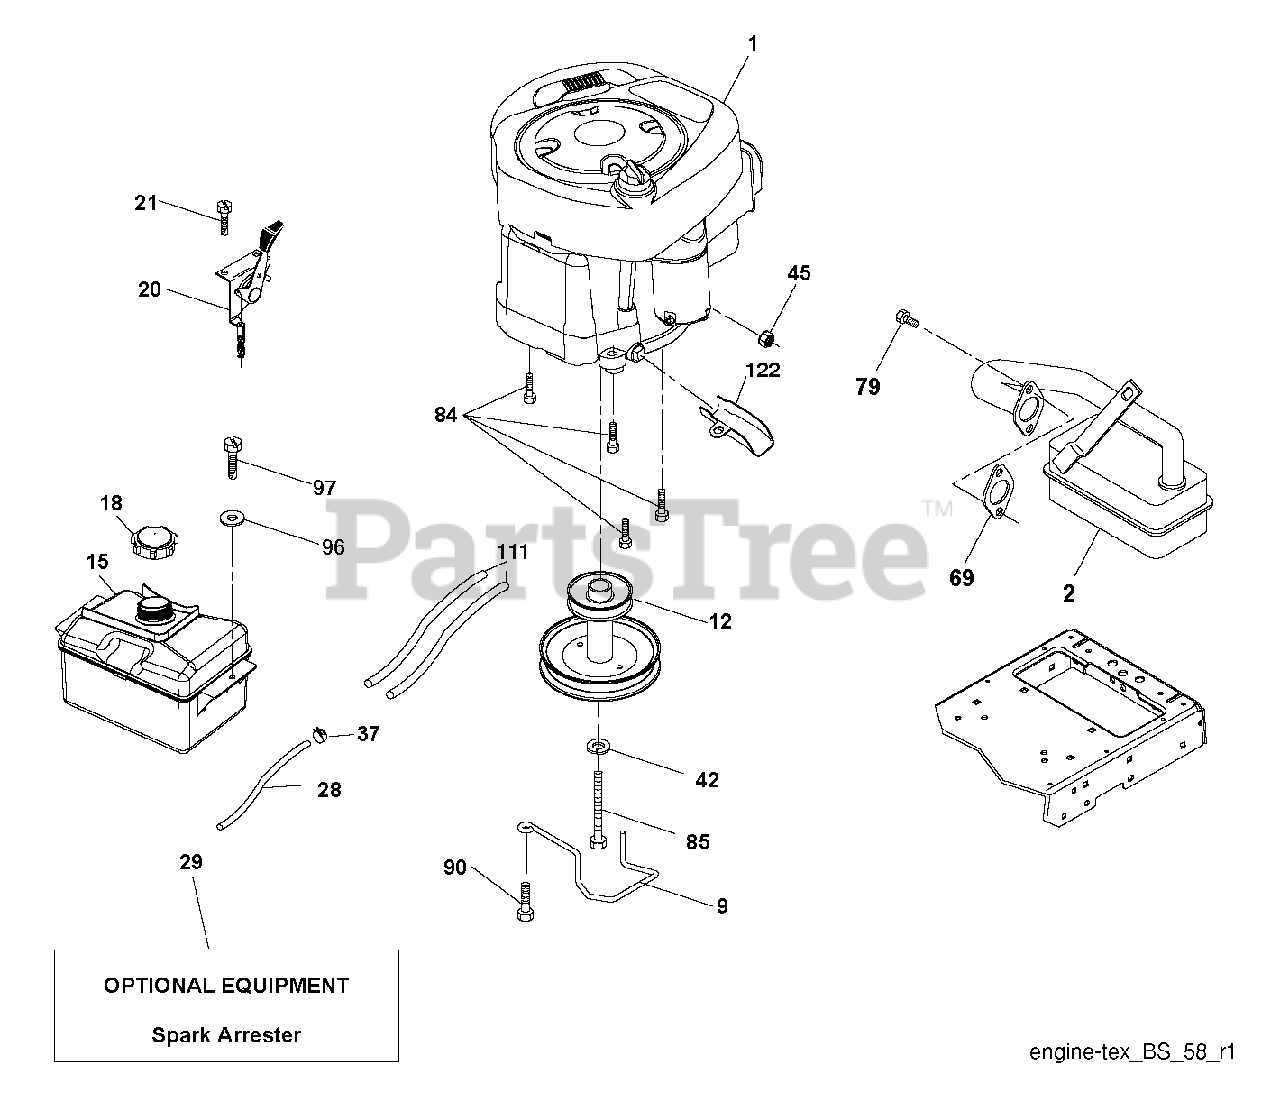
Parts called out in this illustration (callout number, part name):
2	MUFFLER.LT.BRIGGS.14HP.IC/OHV
9	KEEPER.BELT.ENGINE.3.25
12	PULLEY.ENGINE.5.0.PD
15	TANK.ASM.1.5GAL.FRT.W/CAP.EPA
18	CAP ASM.FUEL.2.25"FR.
20	CONTROL.THROTTLE/CHOKE.BLACK
21	SCREW.#10 X 0.750.BOS (2 2)
28	LINE.FUEL.20"FRONT.EMI
29	SPARK ARRESTOR KIT
37	HOSE CLAMP
42	LOCKWASHER
45	NUT
79	SCREW.SOCKET HD.5/16-1
84	SCREW.3/8-16
85	BOLT HEX 7/16-20X4-1/4"
90	SCREW 3/8-16X1
97	SCREW HEXWSHR 1/4-20X3/4
111	RP PURGE LINE
122	EXTENSION DRAIN OIL
